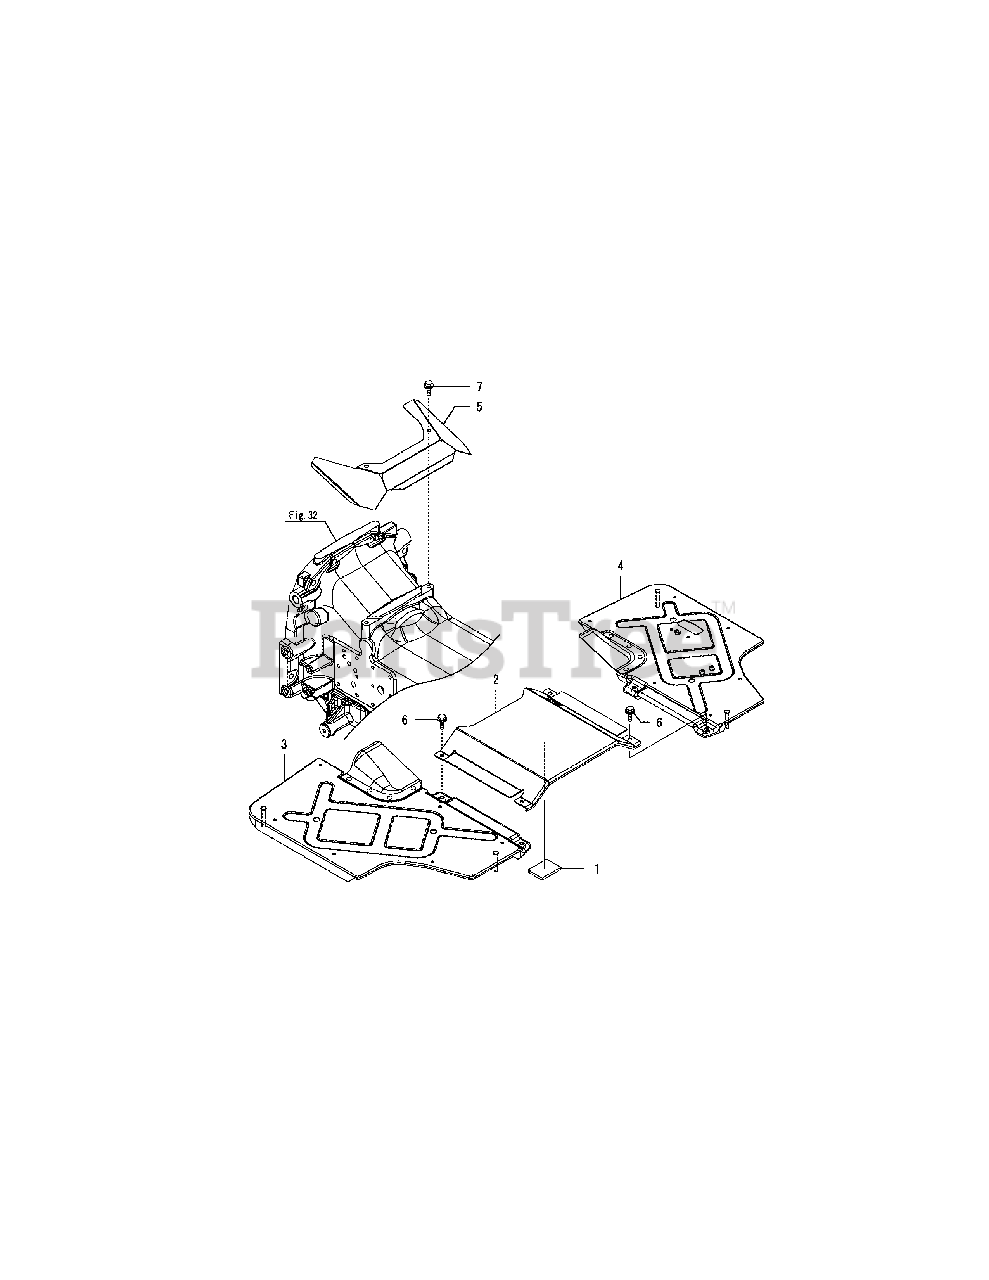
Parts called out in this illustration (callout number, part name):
1	RUBBER, CUSHION
2	PLATE, FLOOR C
3	PLATE ASSY, FLOOR L
4	PLATE ASSY, FLOOR R
6	BOLT M 8X 12 PLATED
7	BOLT M 8X 16 PLATED
